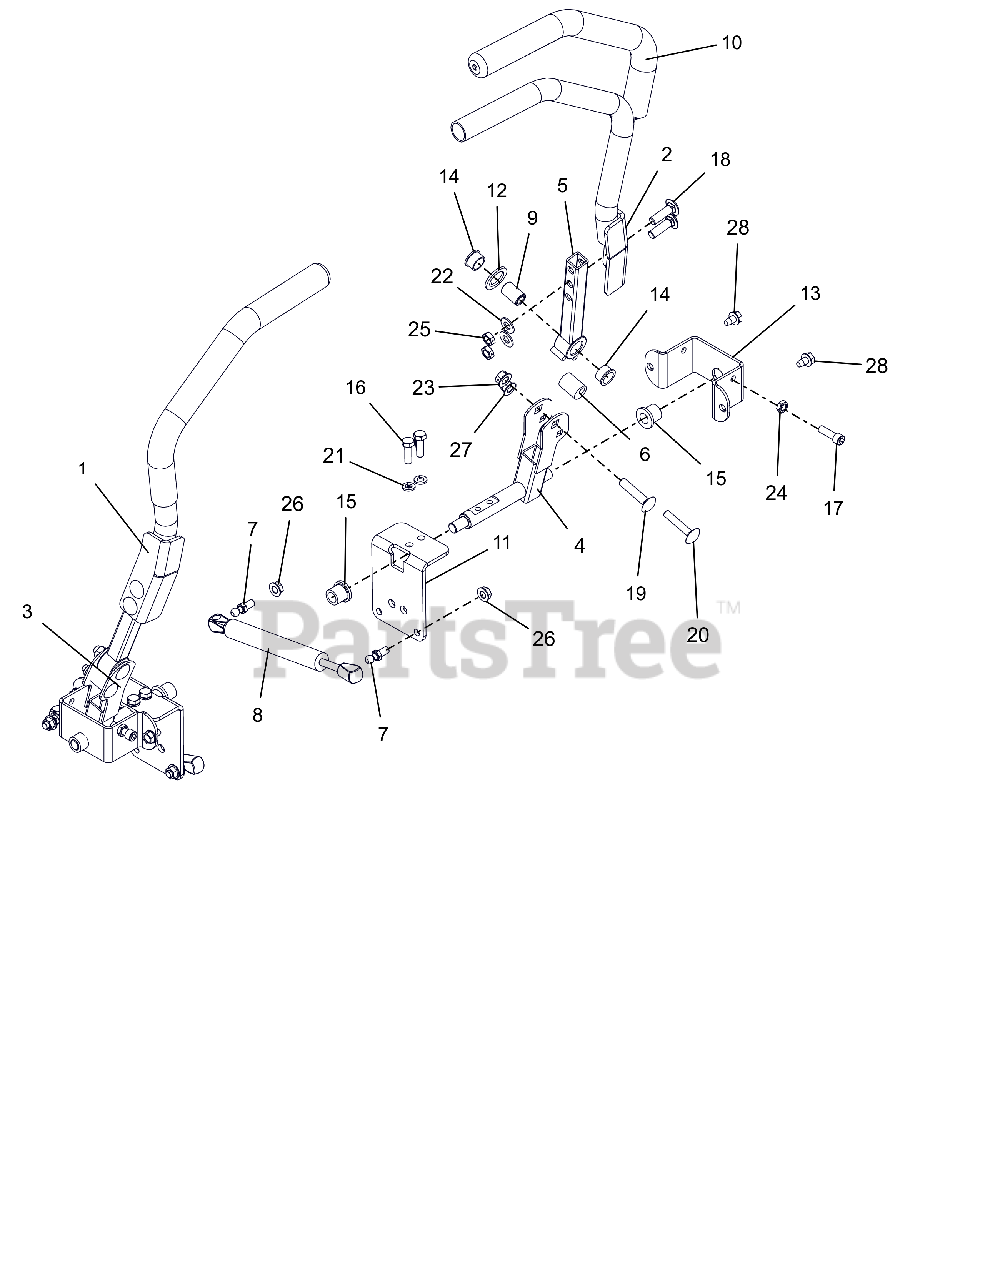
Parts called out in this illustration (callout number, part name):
1	WLDMT, STEERING HANDLE RH
2	WLDMT, STEERING HANDLE LH
3	WLDMT,STEERING ARM LOWER RIGHT
4	WLDMT,STEERING ARM LOWER LEFT
5	WLDMT, UPPER CONTROL ARM
6	BSHG,ECCEN .328X.750X1.01 PM
7	STUD- BALL
8	DAMPER, STABILUS
9	SPACER, .375X.625X.970 (PM)
10	GRIP, HANDLEBAR 15" FOAM
11	BRKT, STEEERING
12	WASHER, FRICTION .875X1.25X.10
13	BRKT, STEERING
14	BSHG-FLG, .625X.75X.450X.875
15	BSHG-FLG .515X.750X.745X1.00NY
16	BLT-HEX .31-18X1.00 GR8 YWZC
17	SCR, SKH .312-18X1.00 G8 SS
18	BLT,RHSSN .38-16X1.25 G5 BFP
19	BLT,RHSSN .38-16X1.75 G5 BFP
20	BLT,RHSSN .31-18X1.75 G5 BFP
21	@WSHR-LK .31X.078 REG YWZC
22	@WSHR-FL-STL.406X.812X.065 YWZ
23	NUT-LK-CTR-FLG .38-16 YWZC
24	NUT- JAM .312-18 YWZC
25	@NUT-LK-CTR-JAM .375-16 YWZC
26	@NUT-LK-TOP-FLG .31-18 YWZC
27	@NUT-LK-NYL-FLG .31-18 YWZC
28	@SCR-TAP .31-18X.50 HWH TR YWZ
